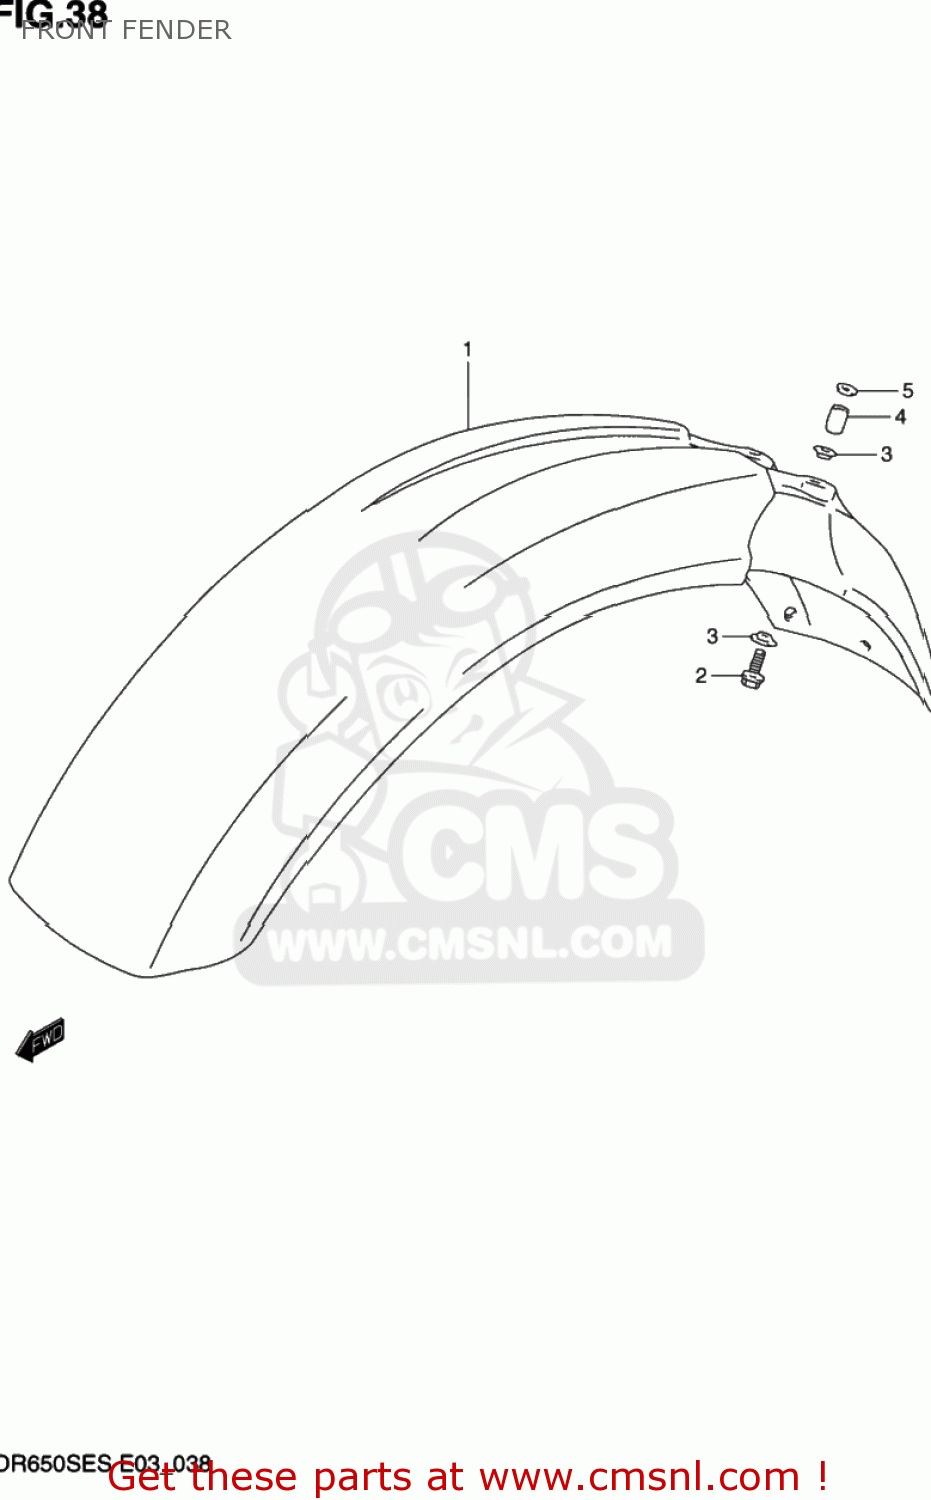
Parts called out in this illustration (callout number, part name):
1	FENDER,FR
2	BOLT
3	WASHER
4	SPACER (6.8X10X16)
5	WASHER
